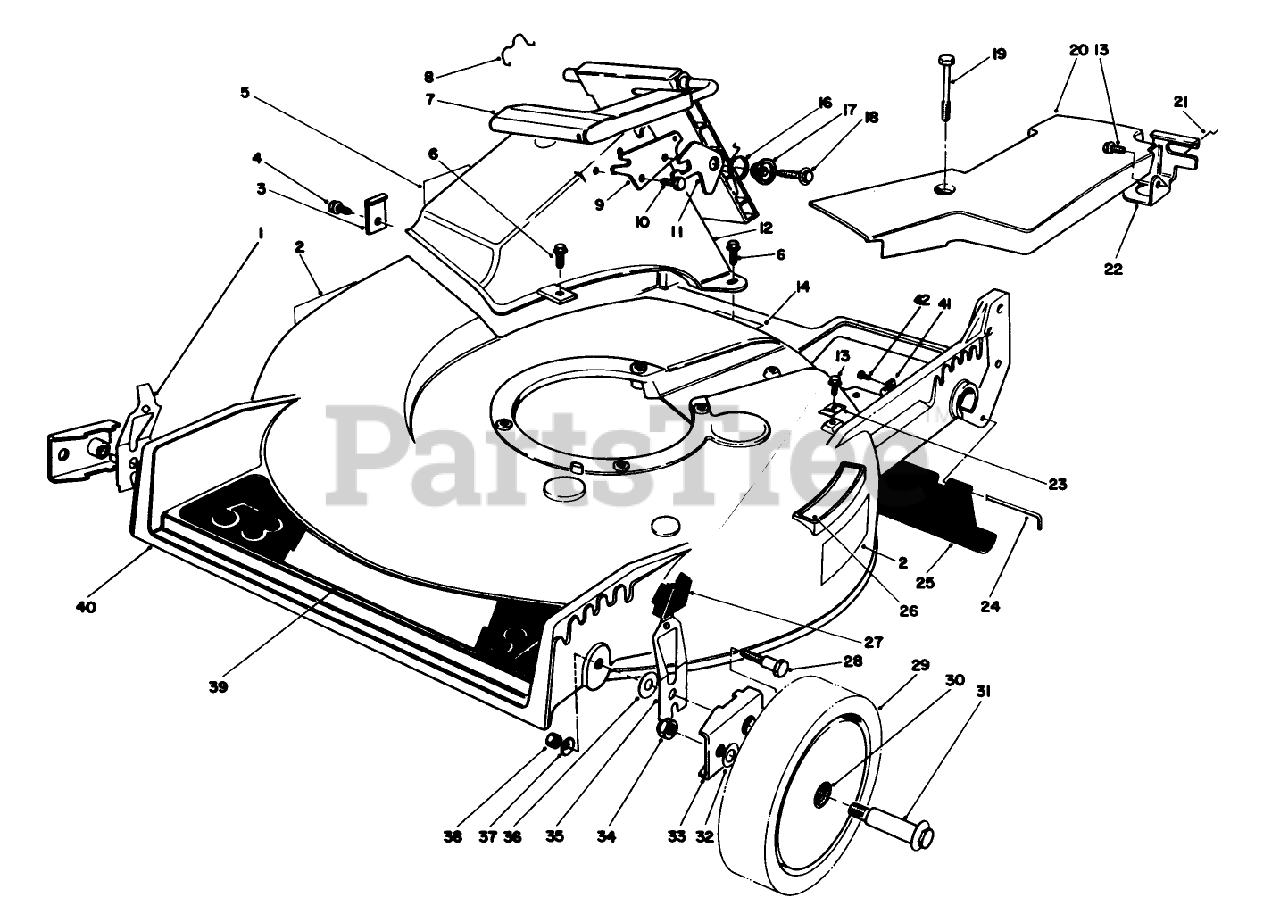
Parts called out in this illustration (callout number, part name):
3	TUNNEL CLIP
4	SCREW
6	SCREW-HWH
8	DOOR RET SPRING
9	DOOR LATCH PLATE
10	SCREW-PLASTITE
11	SAFETY LATCH
13	SCREW-HWHTF
16	TORSION SPRING
17	DOOR SPACER
18	SCREW-HWH
19	SCREW-HWH
21	RETAINER-CABLE
23	CLAMP-CABLE
24	ROD-SHIELD
26	DECAL - STEP PAD INT'L
27	KNOB-ARM
28	PIVOT SCREW
30	BUSHING
31	BOLT-WHEEL
32	WASHER
33	HP PIVOT ARM ASM
36	WASHER-PIVOT
37	WASHER-BELLEVILLE
38	NUT-LOCK, NI
41	CLAMP-CABLE
42	SCREW
